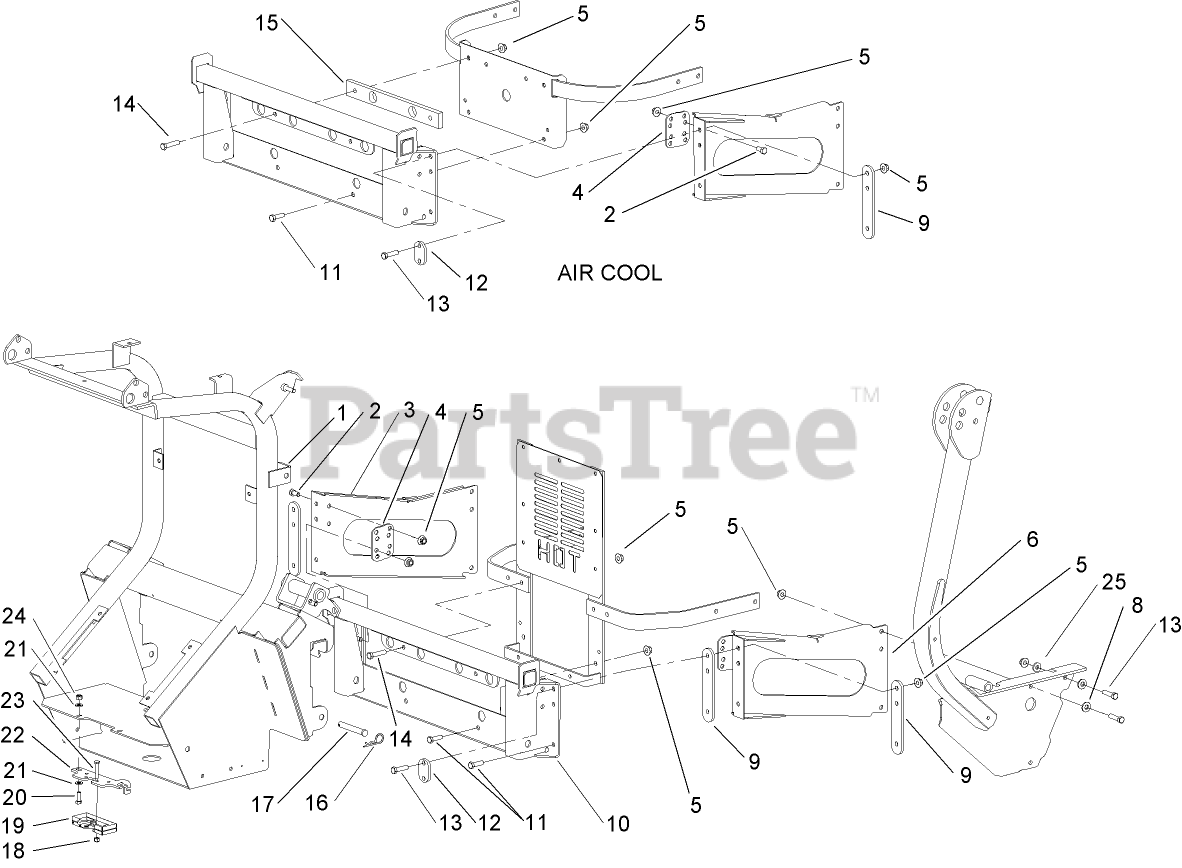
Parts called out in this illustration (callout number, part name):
1	HOPPER FRAME ASM
2	SCREW-HH
3	LH FRAME BRACKET ASM
4	BRACKET-STIFFENER
5	NUT-HF
6	RH FRAME BRACKET ASM
8	WASHER-BELLEVILLE
9	SPACER-FRAME
10	BAGGER MOUNT ASM
11	SCREW-HH
12	SPACER-FRAME, SHORT
13	SCREW-HH
14	SCREW-HH
15	SPACER-FRAME, BAGGER
16	PIN-COTTER
17	PIN-CLEVIS
18	NUT-LOCK, NI
19	LATCH-ROTOR
20	SCREW-HH
21	WASHER-PLAIN
22	BRACKET-LATCH
23	SCREW-HH
24	NUT-LOCK, NI
25	SPACER
